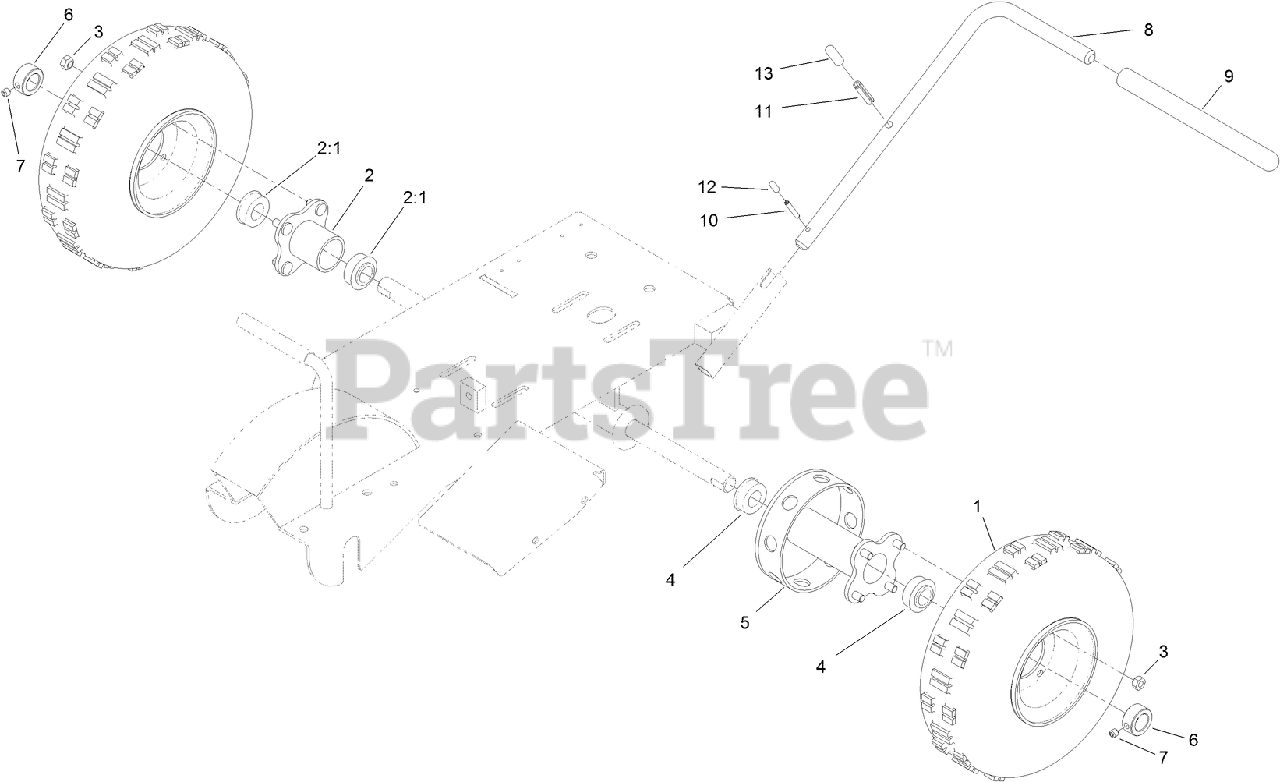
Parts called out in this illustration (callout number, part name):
1	WHEEL AND TIRE ASM
2:1	BEARING-WHEEL
3	NUT-WHEEL
4	BEARING-WHEEL
5	HUB-BRAKE
6	COLLAR-SET
7	SCREW-SET, HSH
8	HANDLE-BRAKE
10	PIN-ROLL, SLOTTED
11	PIN-ROLL
12	CAP-LOWER
13	CAP-UPPER
